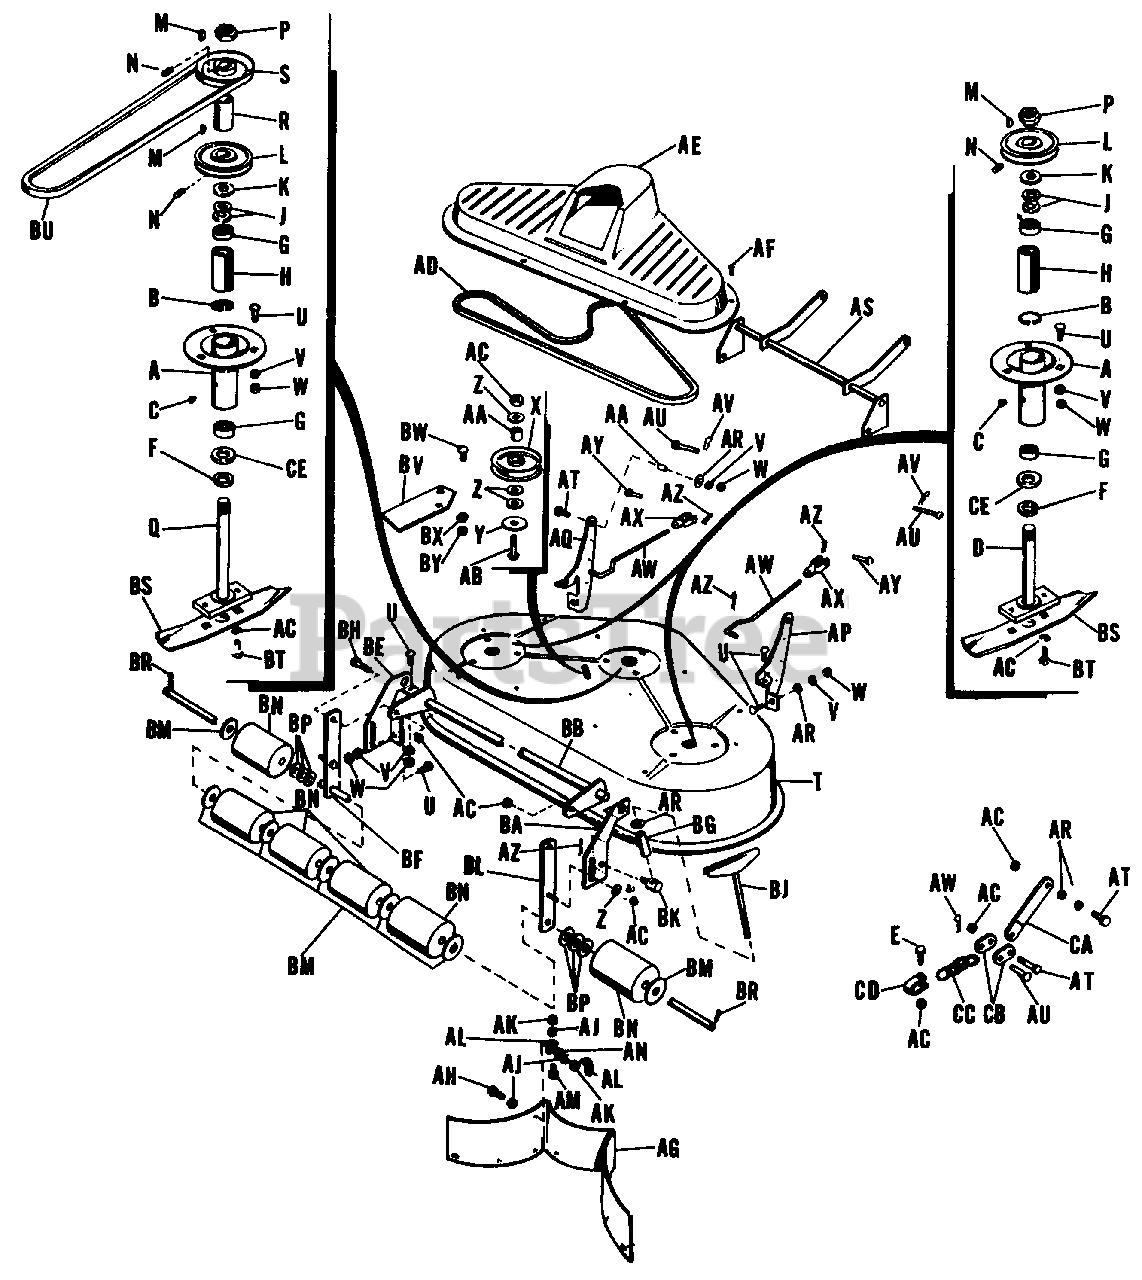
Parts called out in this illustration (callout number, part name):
A	Tube Assembly, Arbor
B	Ring, Backing
C	Plug, Pine
D	Arbor, Assembly
E	Screw, Cap, Hex., 3/8"-16 NC x 1 1/2" lg.
G	Bearing, Single Row, Radial
M	Key, Woodruff #61 3/16" x 5/8" dia.
N	Screw, Set, Cup Point Socket Head, 5/16"-18 NC x 3/8" lg.
P	Nut, Hex., Jam, 3/4"-16 NF
Q	Arbor Assembly Drive
S	Pulley, Cross Drive
U	Bolt, Carriage, 3/8"-16 NC x 3/4" lg. Short Square Neck
V	Washer, Lock, 3/8" Std.
W	Nut, Hex., Full, 3/8"-16 NC
X	Pulley, Idler
Z	Washer, Plain, 5/16" Std.
AB	Bolt, Carriage, 3/8"-16 NC x 1 1/4" lg. Short Square Neck
AC	Washer, Lock, 3/8" Std.
AD	Belt, "V"
AE	Cover, Housing
AF	Screw, Recessed Hex. Head Self Tap, 1/4"-20 NC x 3/8" lg.
AG	Baffle, Mower
AH	Screw, Recessed Hex. Head Self Tap, 1/4" "-20 NC x 7/8" " lg.
AJ	Washer, Lock 1/4 " Std.
AK	Nut, Hex., Full, I/4 "-20 NC
AL	Clip, Baffle
AM	Screw, Cap, Hex., 1/4"-20 NC x 5/8" lg.
AN	Washer, Plain, 1/4" Std.
AP	Bracket, Front, RH
AQ	Bracket, Front, LH
AR	Washer, Plain 3/8" Std.
AS	Hitch Assembly, Mower
AT	Screw, Cap, Hex., 3/8"-16 NC x 1" lg.
AU	Pin, 3/8" dia. x 1" lg., Round Head Rivet
AV	Clip, Spring
AW	Rod, Height Adjustment
AX	Clevis, Adjustment
AY	Pin Clevis
AZ	Pin Cotter, 3/32" dia. x 3/4" lg. w/Ext. Prong
BA	Bracket, Roller, RH
BB	Lever Assembly, Rear
BE	Bracket, Roller, LH
BF	Bar and Shaft Assembly
BG	Socket Assembly, Crank
BH	Screw, Cap, Hex., 3/8"-16 NC x 7/8" lg.
BJ	Screw Assembly, Adjustment
BL	Bar Assembly, Roller
BM	Washer, # 12 Ga. (.109") x 1 7/8" x 2" lg.
BP	Washer (as required)
BR	Pin, Cotter, 3/16" x 1" lg., w/Ext. Prong
BT	Screw Cap, 3/8"-16 x 5/8" lg.
BU	Belt, "V", Cross Drive
BV	Deflector
BW	Bolt, Carriage, 5/16"-18 NC x 3/4" lg., Short Square Neck
BX	Washer, Locks 5/16" Std.
BY	Nut, Hex., Full, 5/16"-18 NC
CA	Lever, Mower Lift
CB	Link Mower Lift
CC	Chain
CD	Clip, Chain
